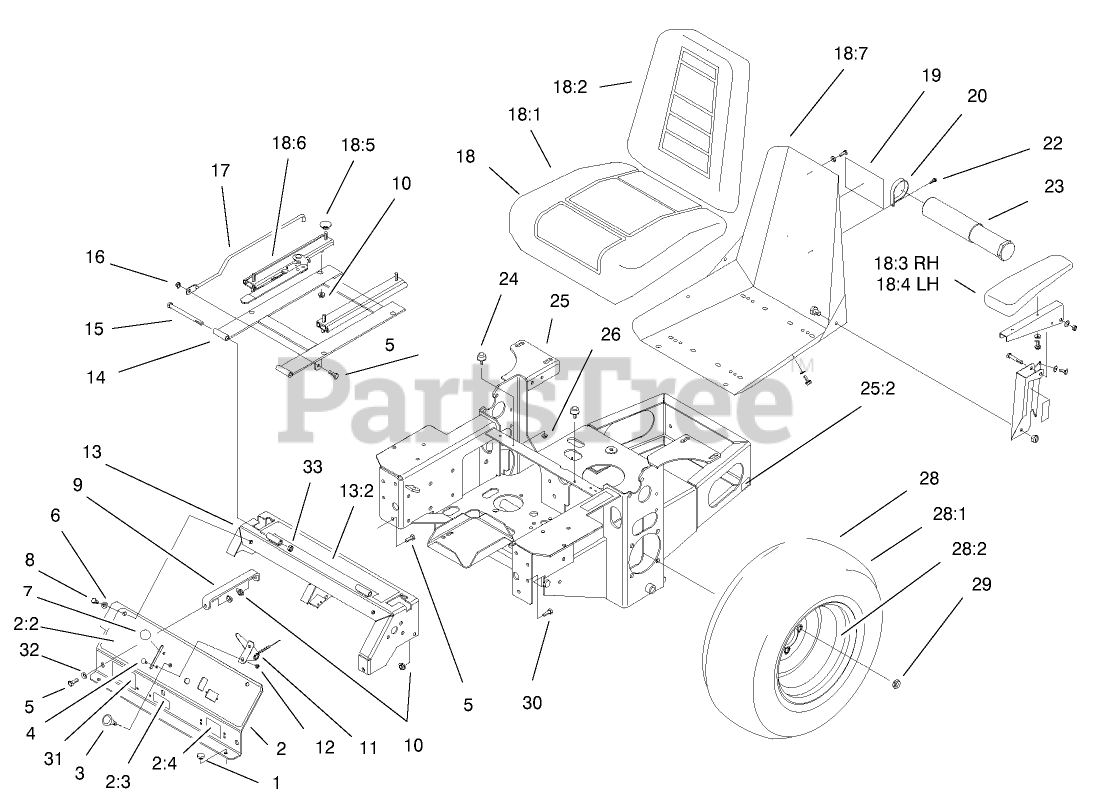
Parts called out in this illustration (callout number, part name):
1	BUMPER
2	CONTROL PANEL ASM
2:2	DECAL-PANEL, CONTROL
2:3	DECAL-VALVE, FUEL
2:4	DECAL-PROTECTION, EAR
3	CONTROL-CHOKE
4	BOLT-CARR
5	SCREW-HH
6	WASHER-PLAIN
7	KNOB-BALL
8	SCREW-HH
9	BRACKET
10	NUT-HF
11	THROTTLE CABLE ASM
12	NUT-LOCK, NI
13	CONSOLE FRAME ASM
13:2	DECAL-CONSOLE, TOP
14	FRAME-SEAT
15	SCREW-HH
16	NUT-LOCK, NI
17	ROD-RETAINER, SEAT
18	SEAT ASM
18:1	CUSHION-SEAT, BOTTOM
18:2	CUSHION-SEAT, BACK
18:3	CUSHION-ARMREST
18:4	CUSHION-ARMREST
18:5	SPACER-TRACK
18:6	TRACK-SEAT
18:7	FRAME-SEAT
19	DECAL
20	CLAMP-R
22	SCREW-HWHTF
23	TUBE-MANUAL
24	BUMPER
25	Main Frame ASM
25:2	DECAL-SURFACE, HOT
26	NUT-LOCK, NI
28	WHEEL AND TIRE ASM
28:1	TIRE
29	NUT-LUG
30	SCREW-HH
31	DECAL-Z149
32	WASHER-FLAT
33	NUT-LOCK, NI
